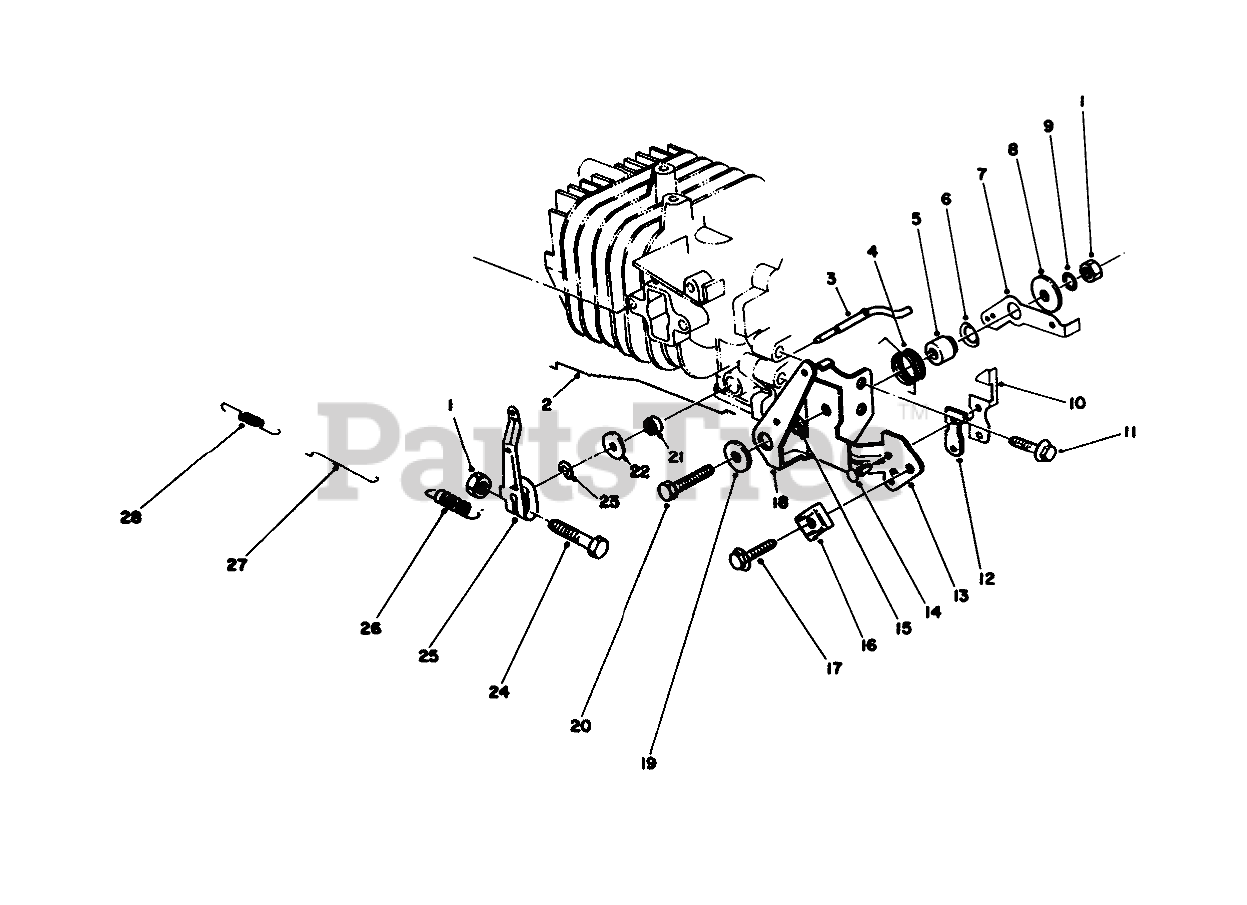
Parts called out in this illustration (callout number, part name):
2	CHOKE ROD
3	Shaft-Govemor
4	SPRING-CHOKE LEVER
5	Gov Lever Spacer
6	Washer-Gov. Spring Lever
7	GOV SPRING LEVER
8	WASHER
9	LOCKWASHER
10	TERMINAL-KILL SWITCH
12	INSULATOR-KILL SWITCH
13	BRACKET-THROTTLE, CONTROL
14	KILL SWITCH RIVET
15	SPACER-CHOKE LEVER
16	CLAMP
18	LEVER-CONTROL, CHOKE
19	WASHER
21	SEAL-OIL
22	WASHER
23	E-RING
25	Lever-Throttle Control
26	GOVERNOR SPRING
27	ROD-CARBURETOR
28	SPRING
